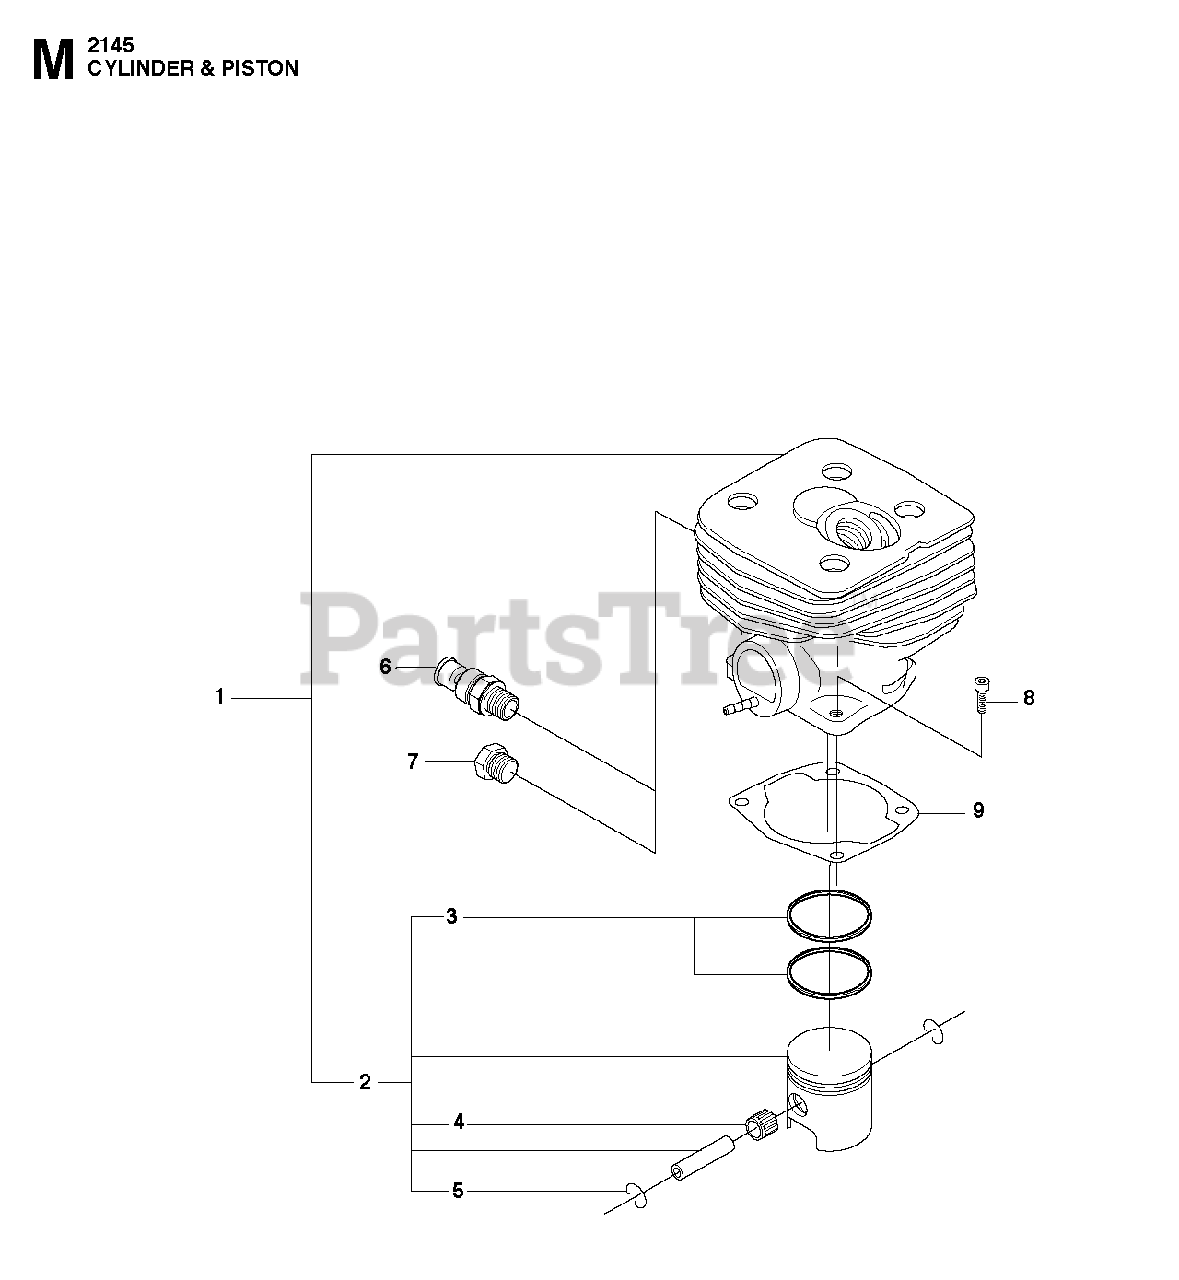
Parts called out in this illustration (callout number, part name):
1	CYLINDER
1	CYLINDER ASSY
2	PISTON ASSEMBLY
2	RP PISTON ASSY
3	PISTON RING
4	RP SUPPORT BUSHING
5	LOCKING RING
6	DECOMPRESSION VALVE
7	CYLINDER PLUG
8	SCREW MC6S 5X20
9	GASKET
